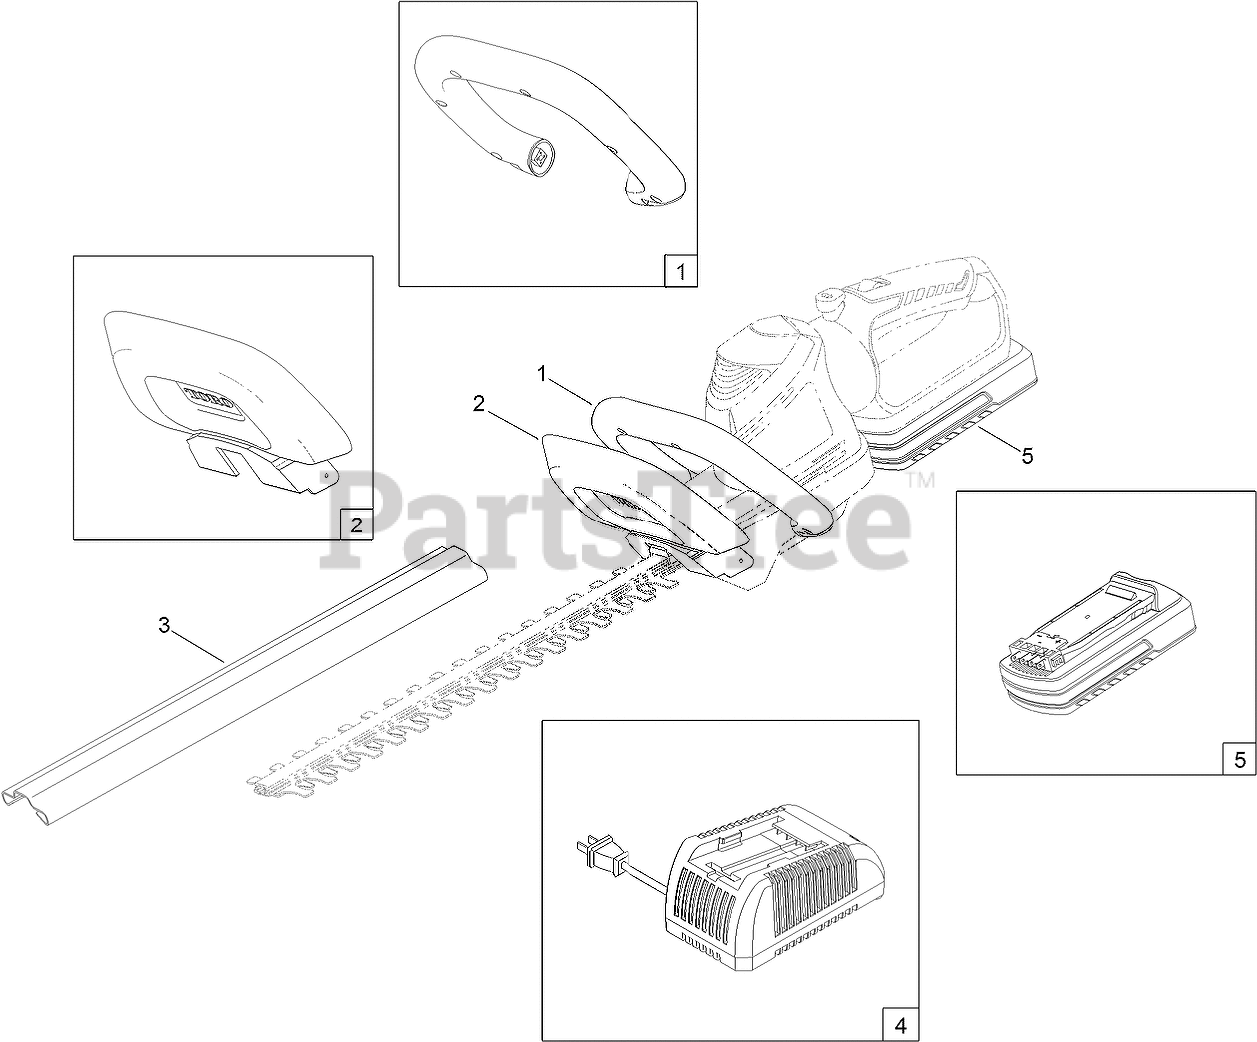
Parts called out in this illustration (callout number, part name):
1	HANDLE-ASSIST
2	GUARD-TRIMMER, HEDGE
3	GUARD-TRIMMER
4	CHARGER-20V MAX, LI ION
5	BATTERY-LI ION, 20V MAX
